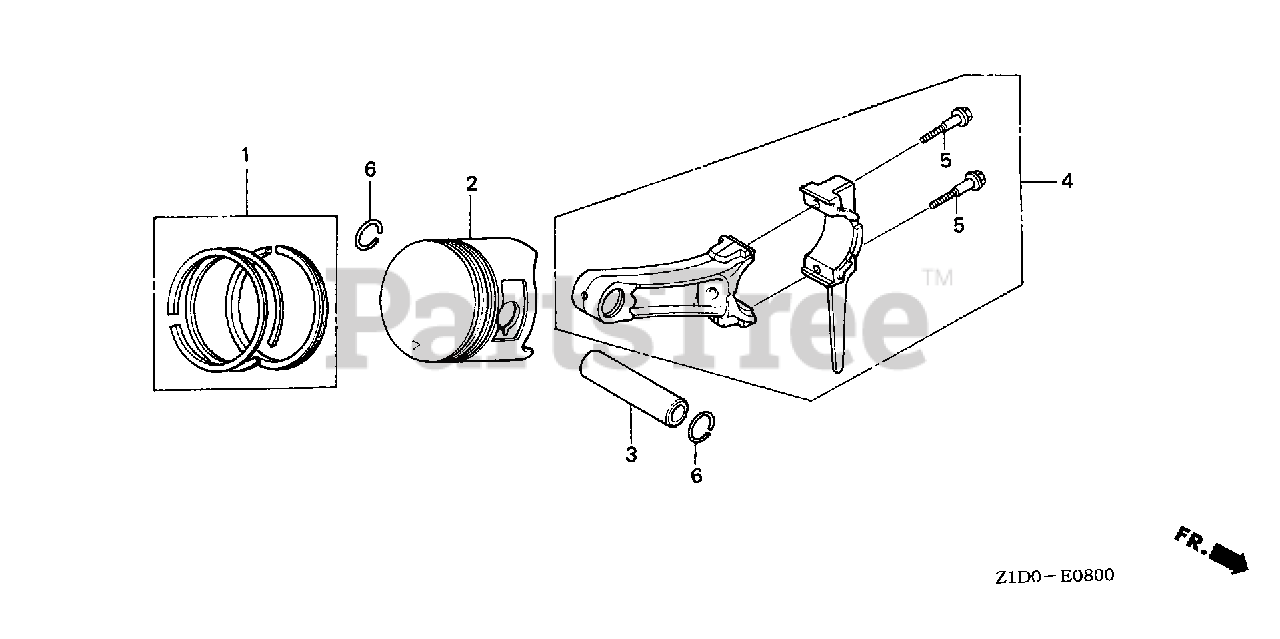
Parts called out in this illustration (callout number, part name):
1	RING SET, PISTON (STD) (TEIKOKU)
1	RING SET, PISTON (0.25) (TEIKOKU)
1	RING SET, PISTON (0.50) (TEIKOKU)
1	RING SET, PISTON (0.75) (TEIKOKU)
2	PISTON (STD)
2	PISTON (0.25)
2	PISTON (0.50)
2	PISTON (0.75)
3	PIN, PISTON
4	ROD ASSY., CONNECTING (0.25 LOWER SIZE)
4	ROD ASSY., CONNECTING (STD)
5	BOLT, CONNECTING ROD
6	CLIP, PISTON PIN (18MM)
